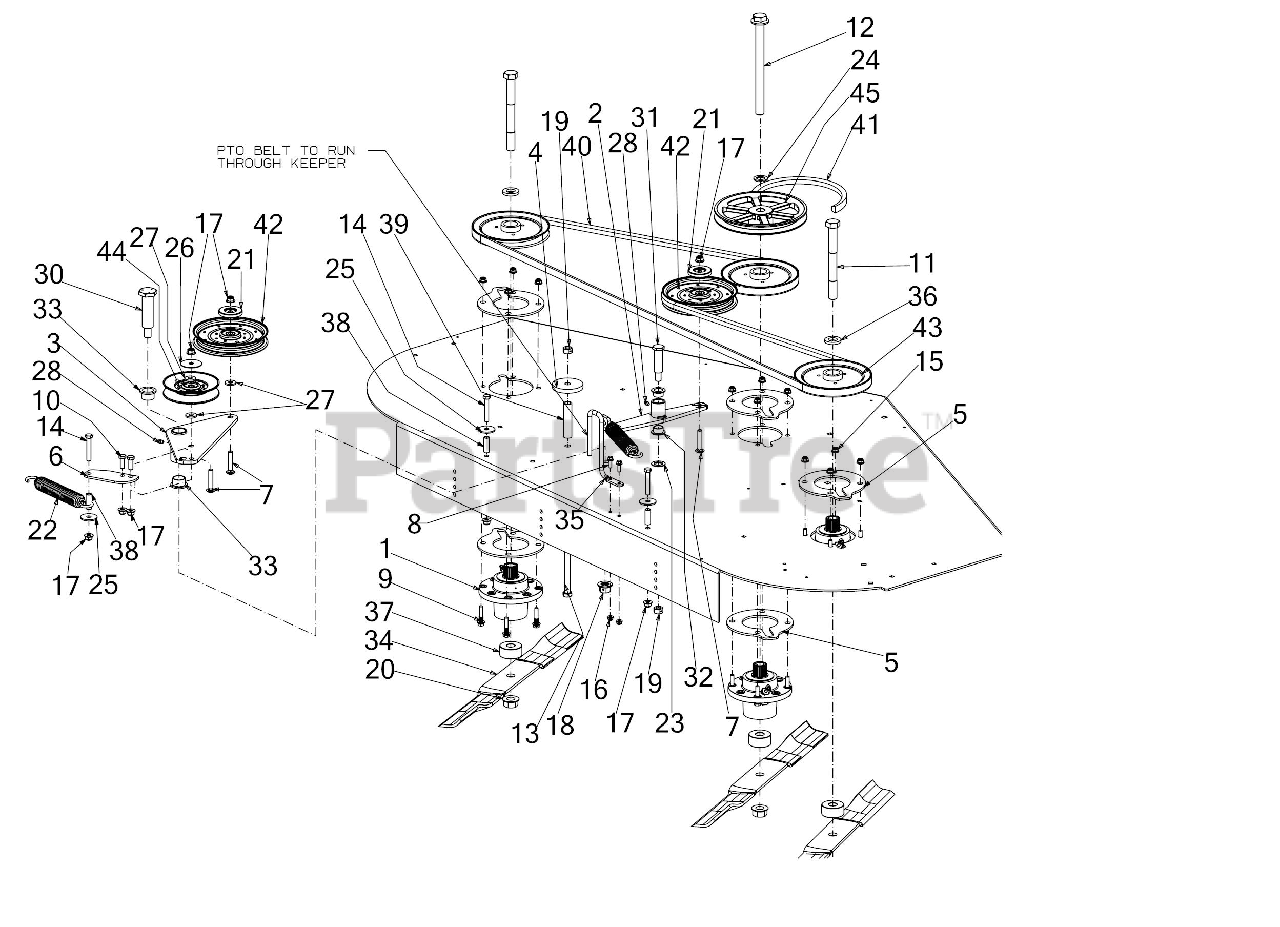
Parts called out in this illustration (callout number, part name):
1	SPINDLE ASSEMBLY
2	IDLER BRACKET
3	PTO IDLER ASSEMBLY
4	SPACER PLATE
6	SPRING ADJUSTMENT BRACKET
7	CARRIAGE BOLT 3/8-16 x 2
8	SCREW 1/4-20 x .75 GR5
9	BOLT 5/16-18 x 1.50 GR5
10	SCREW 3/8-16 x 1 GR5
11	SCREW 3/4-16 x 7.00 GR5
12	SCREW 3/4-16 x 9.00 GR5
13	SCREW 1/2-13 x 4.5 GR 5
14	SCREW 3/8-16 x 2.25 GR5
15	FLANGE LOCK NUT 5/16-18
16	FLANGE LOCK NUT
19	HEX NUT CTR LK 1/2-13
20	HEX FLANGE NUT 3/4
21	PULLEY CAP
22	SPRING 1.25" DIA X 8.5" LONG
23	FLAT WASHER .793ID x 1.24OD x .060
24	SHIM WASHER .76X1.25X.10
25	FLAT WASHER .406X1.500X.105
26	HUB CAP WASHER .406 x 1.92 x .060
27	FLAT WASHER .406ID X1.0 OD
28	GREASE FITTING
30	SHOULDER SCREW 1.0 x 3.15
31	SHOULDER SCREW
32	FLANGE BEARING
34	25" HI-LIFT BLADE
35	ROD KEEPER
36	SPACER .812 ID x .218 LG
41	V-BELT B-SEC X 113.4"
42	IDLER PULLEY
43	SPINDLE PULLEY 7"
44	IDLER PULLEY 5.06 OD
45	SPINDLE DRIVE PULLEY 8.347 DIA
